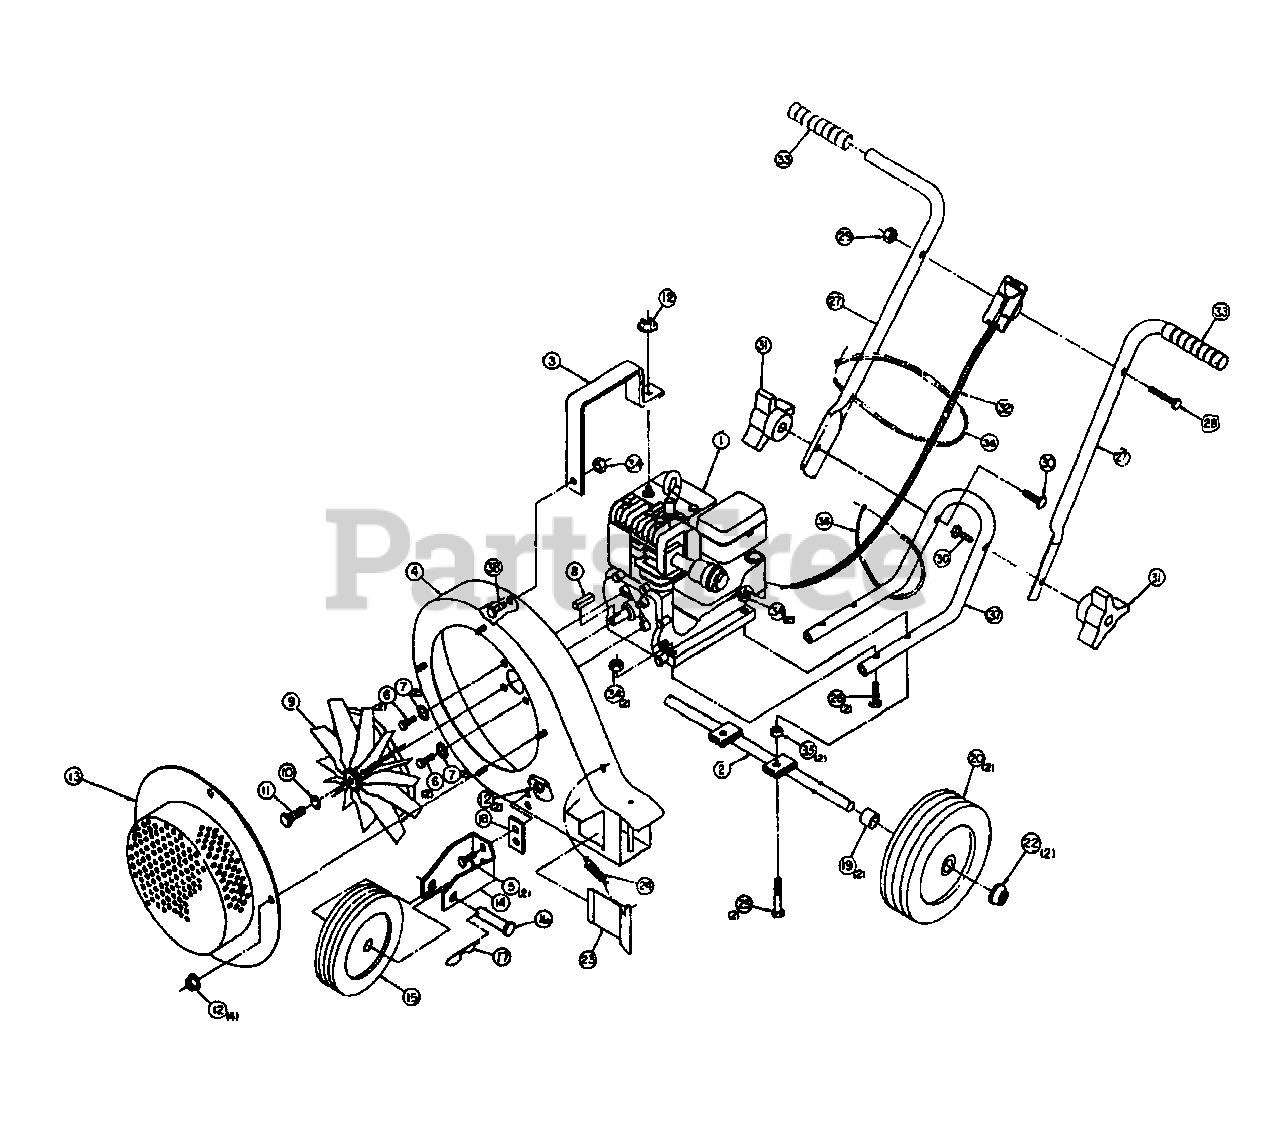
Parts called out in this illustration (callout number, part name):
1	Engine,
2	Axle Assembly
3	Lifting Handle
4	Housing Assembly
5	5/16-18 x 3/4" HHCS
6	5/16-24 x 3/4" HHCS
7	5/16" Split Lockwasher
8	3/16" SQ x 1 1/2" Shaft Key
9	Impeller Assembly
10	1/4" Split Lockwasher
11	1/4-28 x 3/4" HHCS
12	5/16-18 Whizlock Nut
13	Impeller Housing Cover
14	Wheel Bracket
15	Front Wheel 5 x 1.25
16	Clevis Pin 1/2" DIA x 2" LG
17	3/32" Hair Cotter Pin
18	Wheel Bracket Spacer
20	Main Wheel
22	Push Nut Cap
23	Diverter
25	5/16-18 x 2 3/4" HHCS
26	5/16-18 X 2 1/4" HHCS
27	Upper Handle
28	1/4-20 x 2-1/4" HHCS
29	1/4-20 Nylok Locknut
30	5/16-18 x 1-1/2" HHCS
31	Locking Knob
32	Throttle Control
33	Handle Grip
34	5/16-18 Gripco Locknut
35	Engine Spacer
36	Ty-Wrap
37	Lower Handle
38	5/16-18 x 5/8" HHCS, GR5
